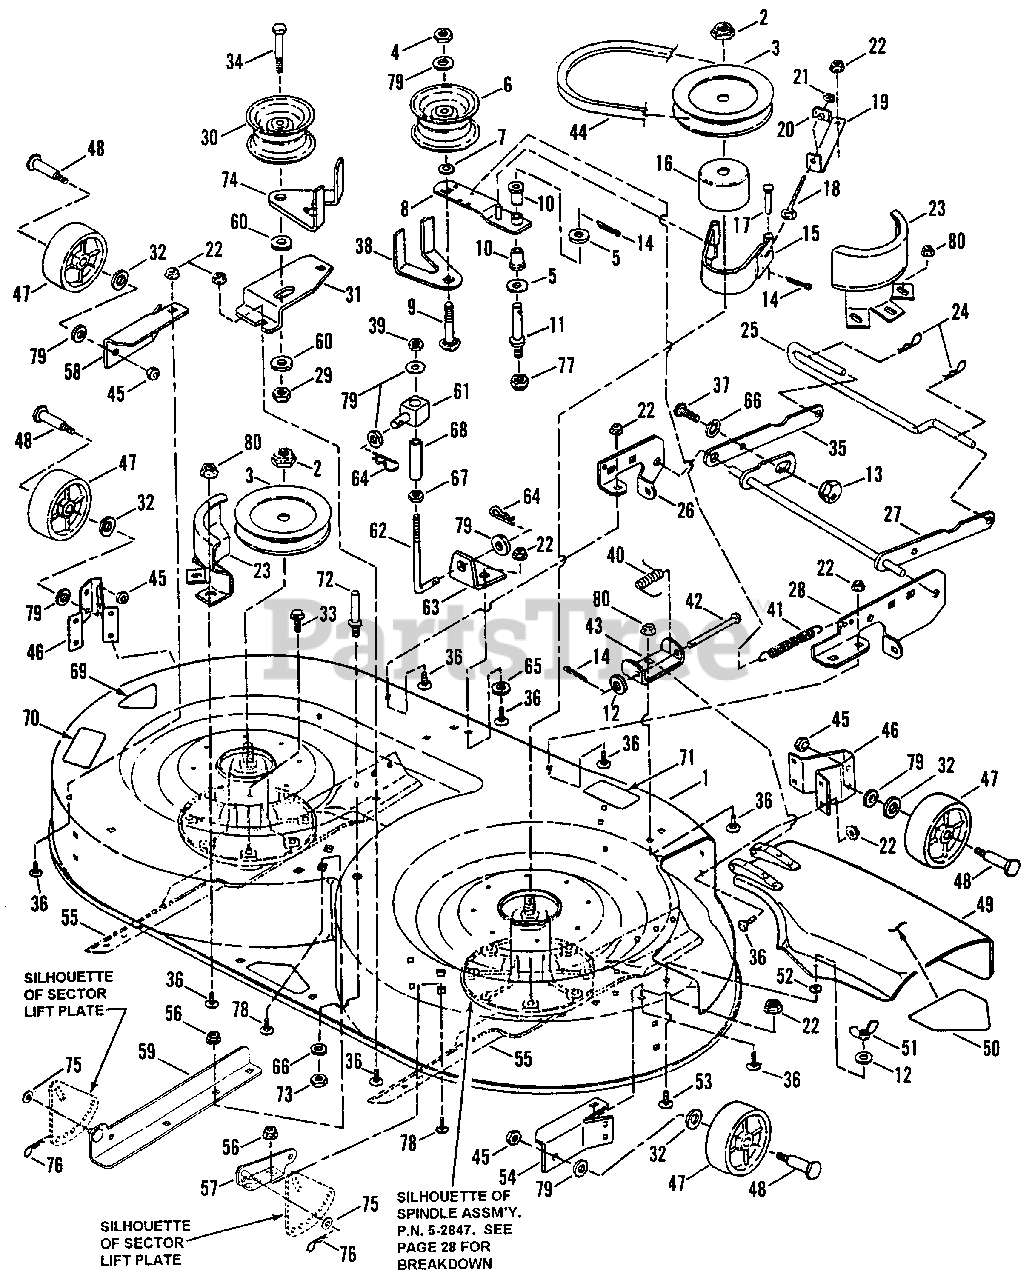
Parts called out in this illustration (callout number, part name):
1	ASSEMBLY, Deck, 38" Cutting
2	NUT, 5/8-16 Hex Nyloc
3	PULLEY, Spindle
4	NUT, 3/8-16 Hex Nyloc
5	WASHER, 3/8" Flat
6	PULLEY, Idler
7	RETAINER, 3/8 Bolt
8	ARM, Idler Pulley
9	BOLT, 3/8-16 x 2-3/4" Short Neck Carriage, Grade 5
10	BUSHING, Flange
11	STUD, Idler
12	WASHER, Flat
13	ECCENTRIC, Leveling
14	COTTER-PIN, 3/32 x 3/4"
15	ASSEMBLY, Brake Band
16	DRUM, Brake
17	PIN, 1/4 x 1 5/8" Clevis
18	BOLT, 1/4-20 Eye
19	ANCHOR, Blade Brake
20	NUT, 1/4-20 "T" Lock
21	NUT, 1/4-20 Hex
22	NUT, 5/16-18 Hex Flange Lock
23	GUARD, Belt
24	PIN, Hair
25	PIN, Deck Hanger
26	BRACKET, Front Lift Arm (Left Side)
27	LIFT, Front Arm
28	BRACKET, Front Lift Arm (Right Side)
29	NUT, 1/2-13 Hex Nyloc
30	PULLEY, Idler
31	BRACKET, idler
32	WASHER, 1/2 Flat
33	SCREW, 3/8-16 x 3/4" Self- Tapping
34	BOLT, 1/2-13 x 3-1/2" Hx. Hd. Cap
35	ARM, Front Lift
36	BOLT, 5/16-18 x 5/8" Short Neck Carriage
37	SCREW, 3/8-24 x 1-1/4" Hex Head Cap, Grade 2
38	GUIDE, Belt
39	NUT, 3/8-16 Hex Center Lock
40	SPRING, Chute Deflector Hinge
41	SPRING, Blade Brake
42	PIN, 5/16 x 3 3/16" Clevis
43	HINGE, Chute Deflector
44	BELT, Drive, 38" Cutting Deck
45	NUT, 3/8-24 Hex Lock
46	BRACKET, Gage Wheel, Front
47	WHEEL, Gage
48	BOLT, 3/8-24 Shoulder
49	ASSEMBLY, Chute Deflector
50	DECAL, Danger
51	NUT, 5/16-18 Wing
52	RETAINER, 5/16 Bolt
53	BOLT, 5/16-18 x 3/4" Short Neck Carriage, Grade 5
54	BRACKET, Wheel (Right Side)
55	BLADE, 19-1/2"
56	NUT, 3/8-16 Hex Flange Lock
57	BRACKET, Rear Deck Lift (Right Side)
58	BRACKET, Wheel (Left Side)
59	BRACKET, Rear Deck Lift (Left Side)
60	WASHER, .406 I.D. x 1.50 O.D. x .20
61	SWIVEL, Lift
62	BOLT, "J"
63	BRACKET, Angle (Front)
64	PIN, Hair
65	WASHER, 7/16 Flat
66	WASHER, 3/8 Internal Tooth Lk.
67	NUT, 3/8-16 Hex, Grade 5
68	SPACER, Lift
69	DECAL, 38"
70	DECAL - CAUTION (Rotating Blades)
71	DECAL - CAUTION
72	STOP, Deck
73	NUT, 3/8-24 Hex
74	GUIDE, Belt
75	WASHER, 3/8" Flat
76	PIN, Hair, .093 x 1.50"
77	NUT, 5/16-24 Hex Lock
78	BOLT, 3/8-16 x 3/4" Carriage
79	WASHER, 3/8" Flat
80	NUT, 5/16-18 Hex Lock, Gr. 5
